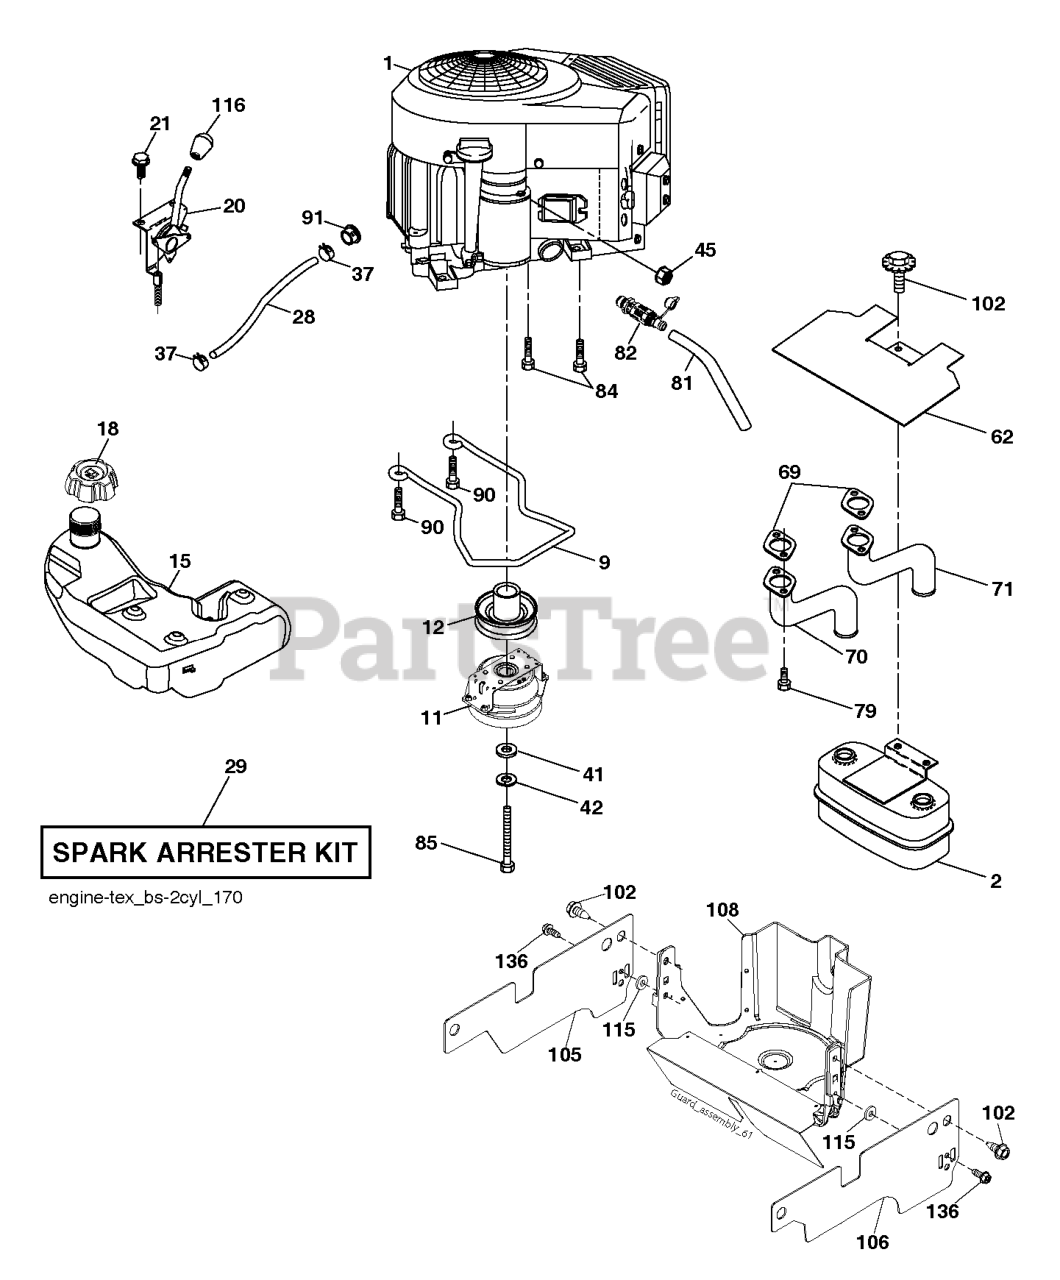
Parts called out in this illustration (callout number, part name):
2	MUFFLER.ASM.TWIN.MNTG.BRACKET
9	KEEPER.BELT.ENG.4.25"2.BLT.431
11	CLUTCH.OGURA.4.4PD.GT1.5-EH13V
12	PULLEY.ENGINE.TUFFTORQ
15	FUEL.TANK.ASM.3.0GAL.REAR.2019
18	CAP ASSY FUEL 3" GRAY
18	FUEL CAP
20	THROTTLE.PRO.RSTART. 38
28	LINE.FUEL.64"REAR.EMIS
29	KIT.SPARK ARRESTOR 794945 B&S
37	HOSE CLAMP
62	SHIELD.HEAT.MUFFLER
69	GASKET.MUFFLER
70	EXHAUST.TUBE.LH.BS/TWIN
71	EXHAUST.TUBE.RH.B&S.TWIN.INTEK
81	TUBE, DRAIN OIL ASM.
82	VALUE.OIL.DRAIN
84	SCREW.3/8-16
85	CLUTCH BOLT7/16-20X3.5 GR524HR
90	SCREW 3/8-16X1
91	BUSHING.1.375OD
102	SCREW
105	SHIELD.SIDE.LH.3842"TEX FRN.BK
106	SHIELD.SIDE.LH.3842"TEX FRN.BK
108	COVER ENGINE PULLEY COVER WITH
116	KNOB - SHIFT
